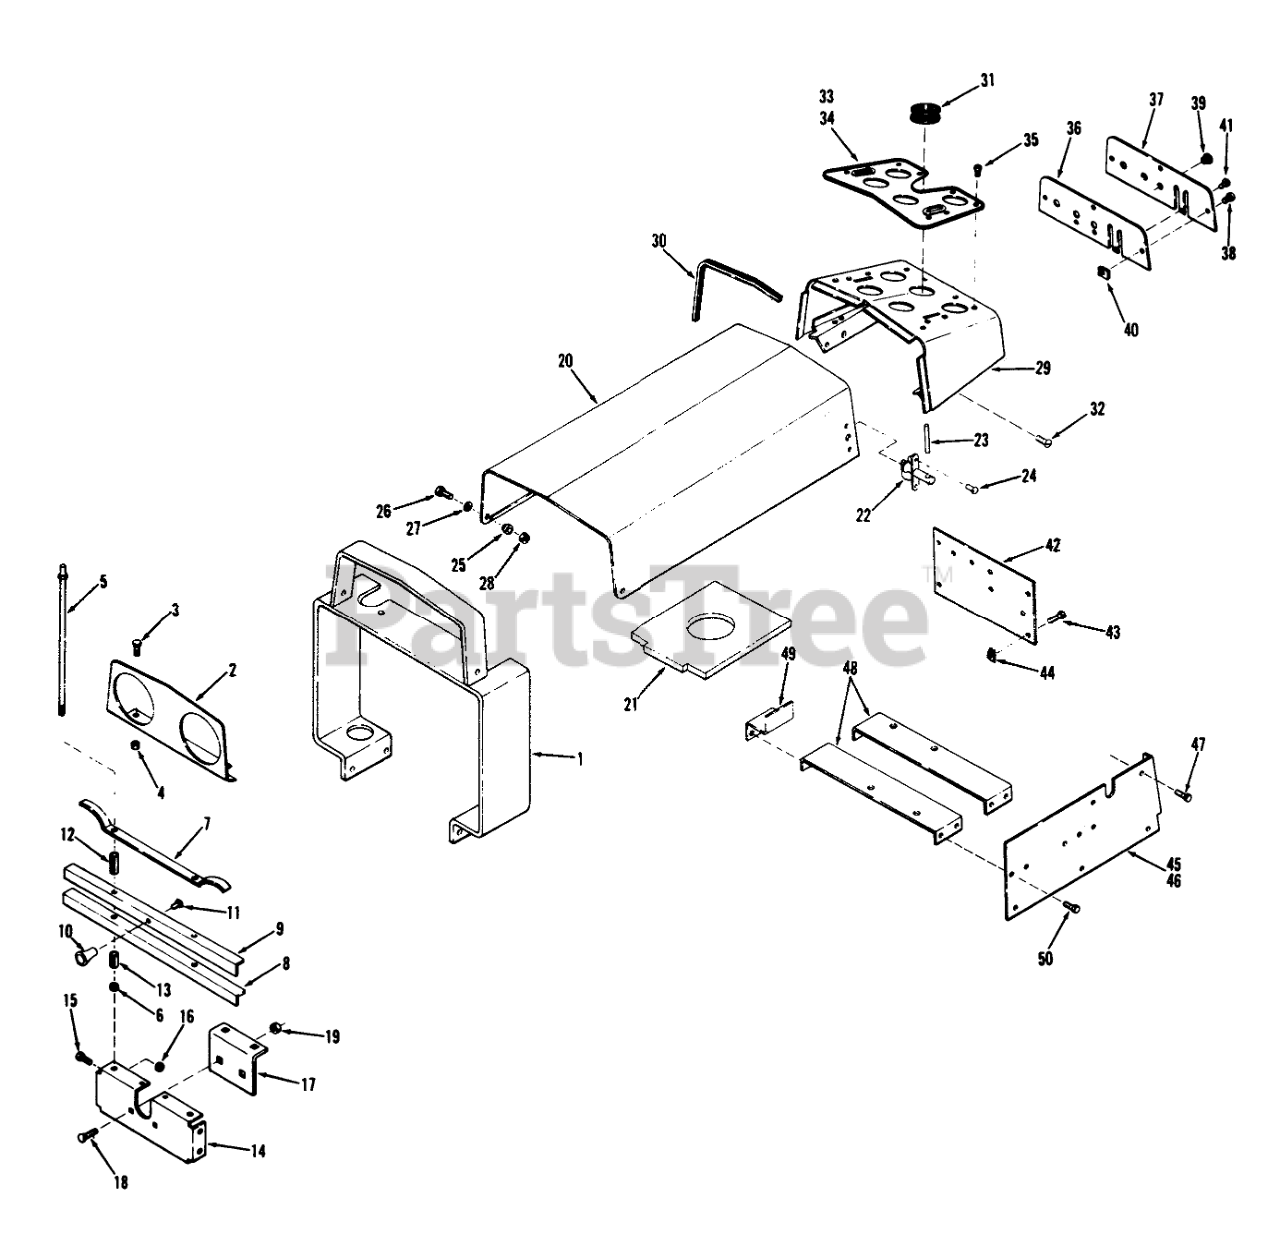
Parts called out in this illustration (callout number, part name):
1	Asy-Grille Shroud
2	Light Bracket
3	HHCS
3	Bolt
4	Nut
5	ROD-GRILLE
6	Nut
7	SPRING GRILLE
7	Nut
8	ANGLE-GRILLE
9	ANGLE-GRILLE
11	SCREW
12	Spacer
13	Spacer
14	Cover-Front
15	Bolt
16	NUT
17	Cover
18	Bolt-Hex
19	Nut
20	Assy-Hood
21	INSULATION FOAM
22	Latch
24	RIVET
25	Bushing
26	HHCS
27	WASHER 5/16 SAE
28	Nut
29	Control Housing
30	Edge Trim
31	GROMMET
32	SCREW
33	Plate-Instrument
34	Plate-Instrument
35	Plate Screws
36	Plate
37	Plate-Rear Instrument
38	Screw
39	PLUG BUTTON
40	Speed Nut
41	Plate Screws
42	Panel
43	Screw
45	Panel-Console RH
46	Panel-Console LH
47	SCREW
48	Battery Support
49	Battery Bracket
50	SCREW
